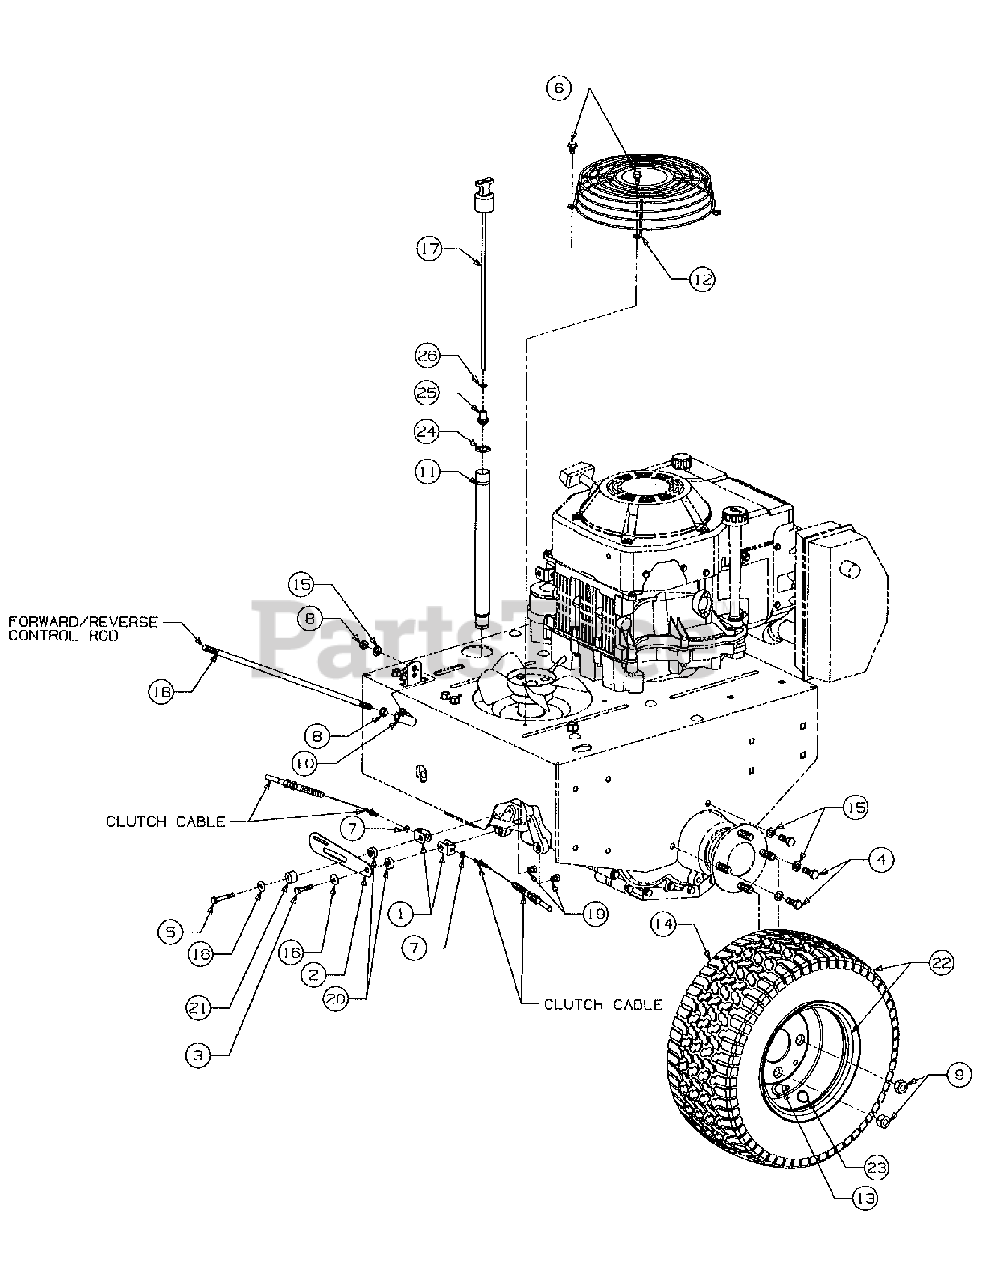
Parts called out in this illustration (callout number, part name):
1	U-Clevis, Clutch Cable
2	Plate, Parking Brake Switch Mount
3	Screw, Hex Cap 1/4-28 x 1.25 Gr 5
4	Screw, Hex Cap 3/8-16 x 1.0 Gr 5
5	Screw, Hex Cap 1/4-28 x 1.75 Gr 5
6	Screw, Hex Wash Hd Tapp, 5/16-18 x .50
7	Nut, Hex Jam, #10-32
8	Nut, Hex Jam, 3/8-24 Gr 5
9	Nut, Lug 1/2-20
10	Ball Joint, 3/8-24
11	Tube, Oil Fill
12	Guard, Fan Cover
13	Valve, Tubeless Air
14	Tire, Turf Chief, 16 x 6.50-8
15	Washer, Lock 3/8
16	Washer, Bell, .265 x .75 x .062 Thk
18	Rod, F/R Control
19	Nut, Clevis Spacer, 1/4-28
20	Spacer, Clevis
21	Spacer, Switch Engagement
22	Wheel & Tire Assembly Complete 16 x 6.50/8
23	Label, Inflation
25	Seal, Rubber
26	Washer, Plain 5/16
